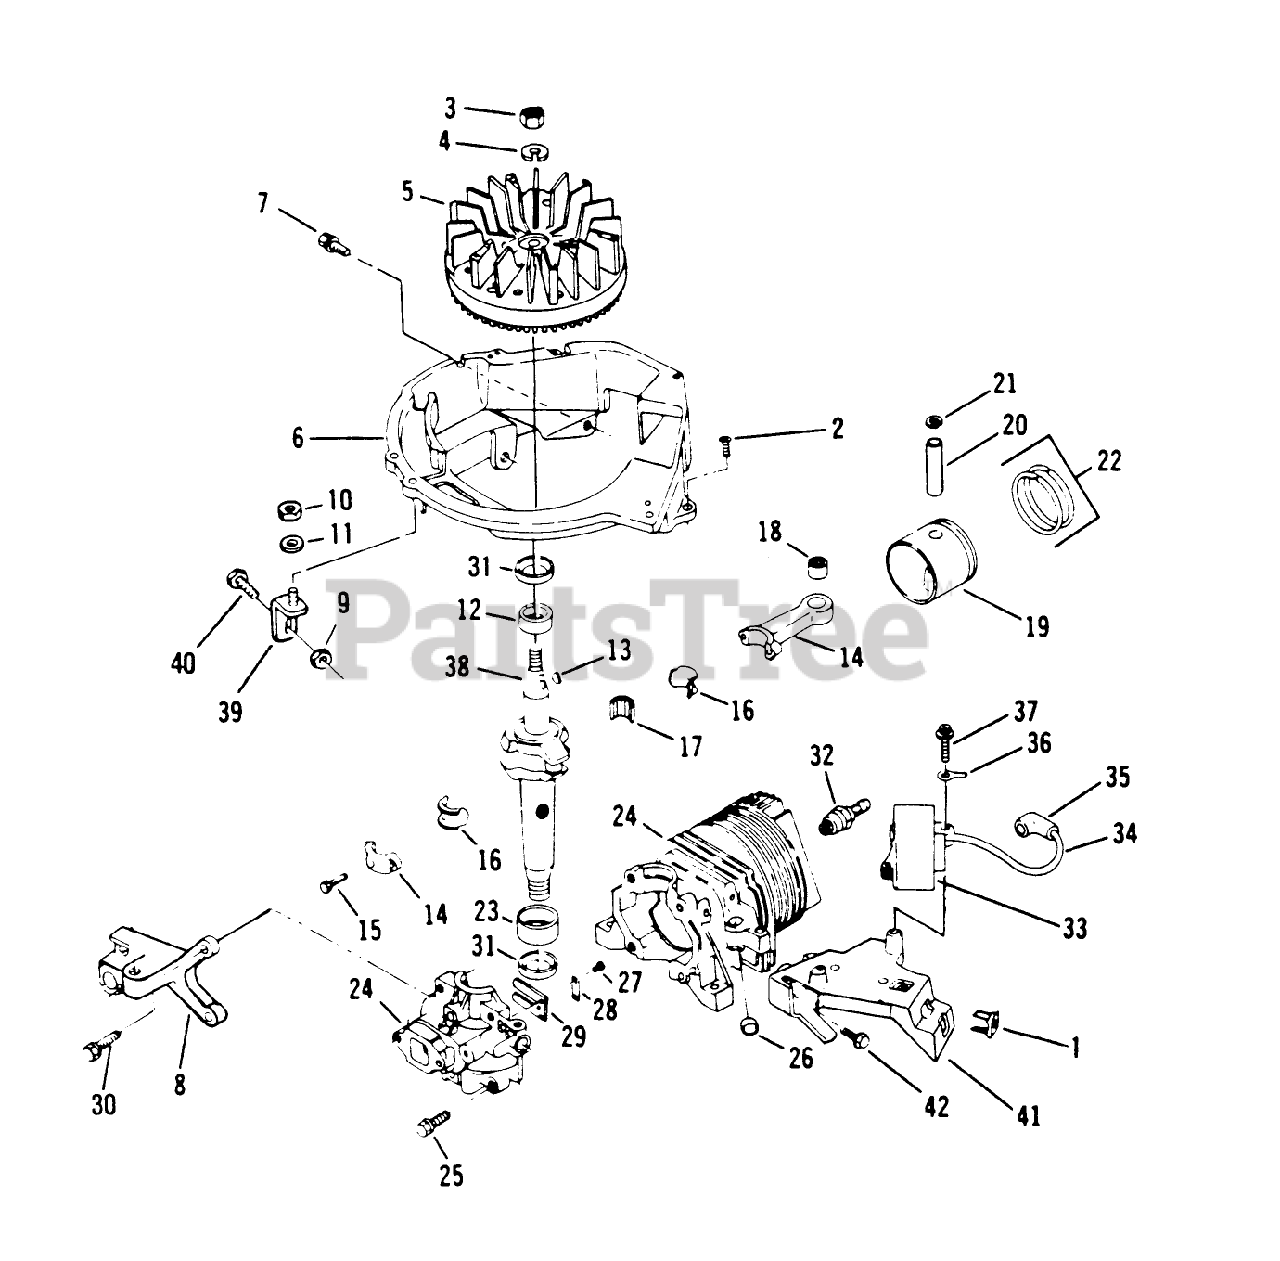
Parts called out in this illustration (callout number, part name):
1	NUT-CLIP
2	SCREW F
3	NUT
5	FLYWHEEL ASSY F
7	SCREW-SEMS
8	BRACKET-BRAKE F
9	NUT-LOCK F
10	LOCKNUT E
11	WASHER S
12	BEARING V
13	KEY
15	SCREW-HSH
16	LINER ASM
17	BEARING-NEEDLE
18	BEARING AY F
21	RING-RETAINING
23	BEARING V
25	SCREW S
26	PLUG-CORE VF
27	SCREW-HH
28	PLATE-BACKUP, REED
31	SEAL-OIL
34	HT LEAD&COVER XEV
36	TERMINAL S
39	BRACE AY F
40	BOLT F
41	BRACKET S
